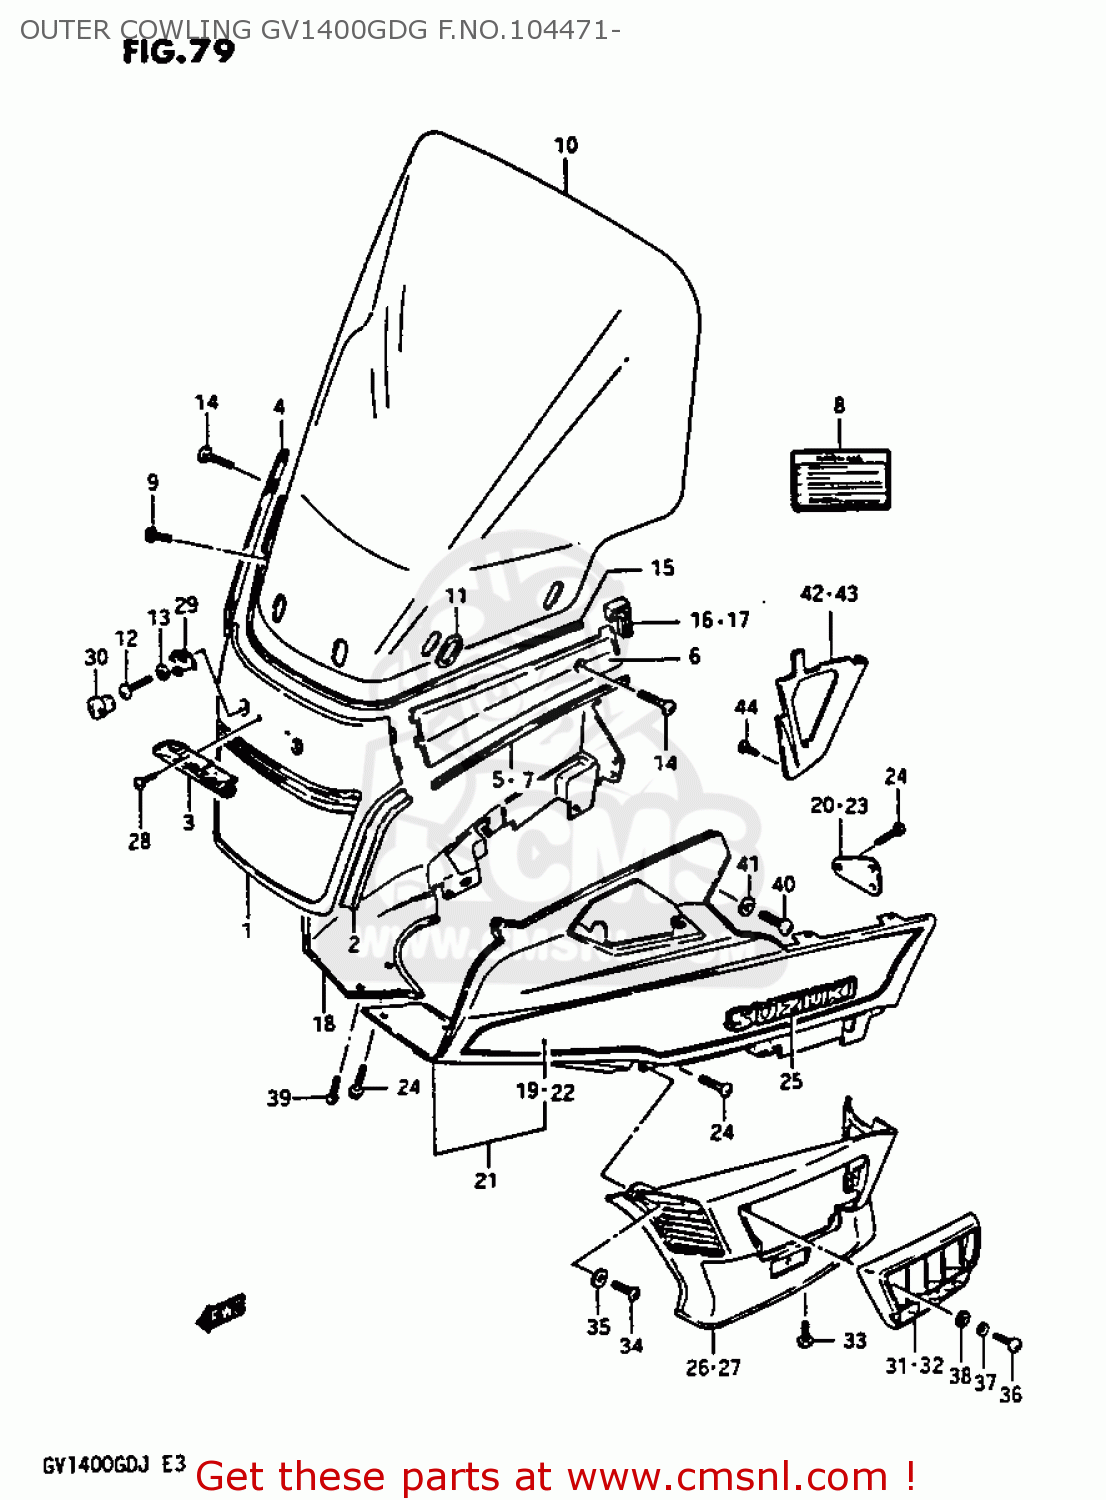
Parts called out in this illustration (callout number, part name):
1	COVER,COWLING,FRONT,CENTER
2	MOLDING,FRONT COVER,LOWER
3	EMBLEM,COWLING,FRONT
4	COVER,COWLING,FRONT,RIGHT
5	MOLDING,FRONT COVER SIDE
6	COVER,COWLING,FRONT,LEFT
7	MOLDING,FRONT COVER SIDE
8	LABEL (WARNING SCREEN)
9	SCREW
10	SCREEN ASSY,COWLING
11	WASHER,SCREEN
12	SCREW
13	WASHER
14	SCREW
15	SEAL,FRONT COVER,CENTER
16	CAP,COWLING FRONT COVER END
17	CAP,COWL FR COVER END,L
18	BODY,COWLING,RIGHT
19	TAPE SET,COWLING BODY
20	BRACKET,COWLING BODY,RIGHT
21	BODY,COWLING,LEFT
22	TAPE SET,COWLING
23	BRACKET,COWLING BODY,RIGHT
24	SCREW
25	EMBLEM,COWLING SIDE,LEFT
26	COVER ASSEMBLY,COWLING
27	COVER,COWLING SIDE,LEFT
28	SCREW
29	PLATE,FRONT COVER LOCK
30	CAP,FR COVER
31	LOUVER,SIDE COVER,RIGHT
32	LOUVER,SIDE COVER,LEFT
33	SCREW (M6X1X16)
34	SCREW
35	WASHER (4.3X13X0.80)
36	SCREW 4X16
37	LOCK WASHER
38	WASHER
39	SCREW
40	SCREW
41	WASHER
42	UNDER COVER, FRAME
43	COVER,COVER FRAME,UPPER
44	SCREW
